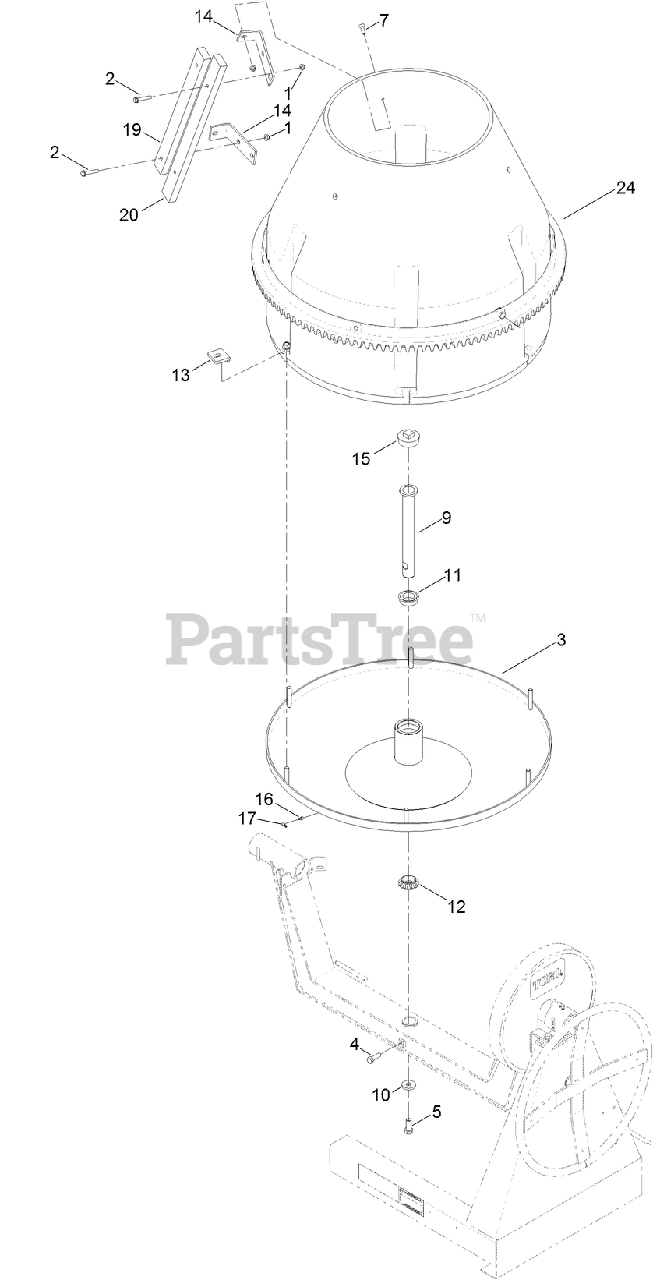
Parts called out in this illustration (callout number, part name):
1	NUT-HF, NI
2	SCREW-HHF
4	SCREW-HH
5	SCREW-HH
7	SCREW-HSFH
9	SPINDLE
10	WASHER-FLAT
11	BEARING
12	BEARING-ROLLER
13	CLAMP-DRUM
14	BRACKET-PADDLE
16	FITTING
17	CAP-PLUG
19	PADDLE
20	PADDLE
24	DRUM ASM
